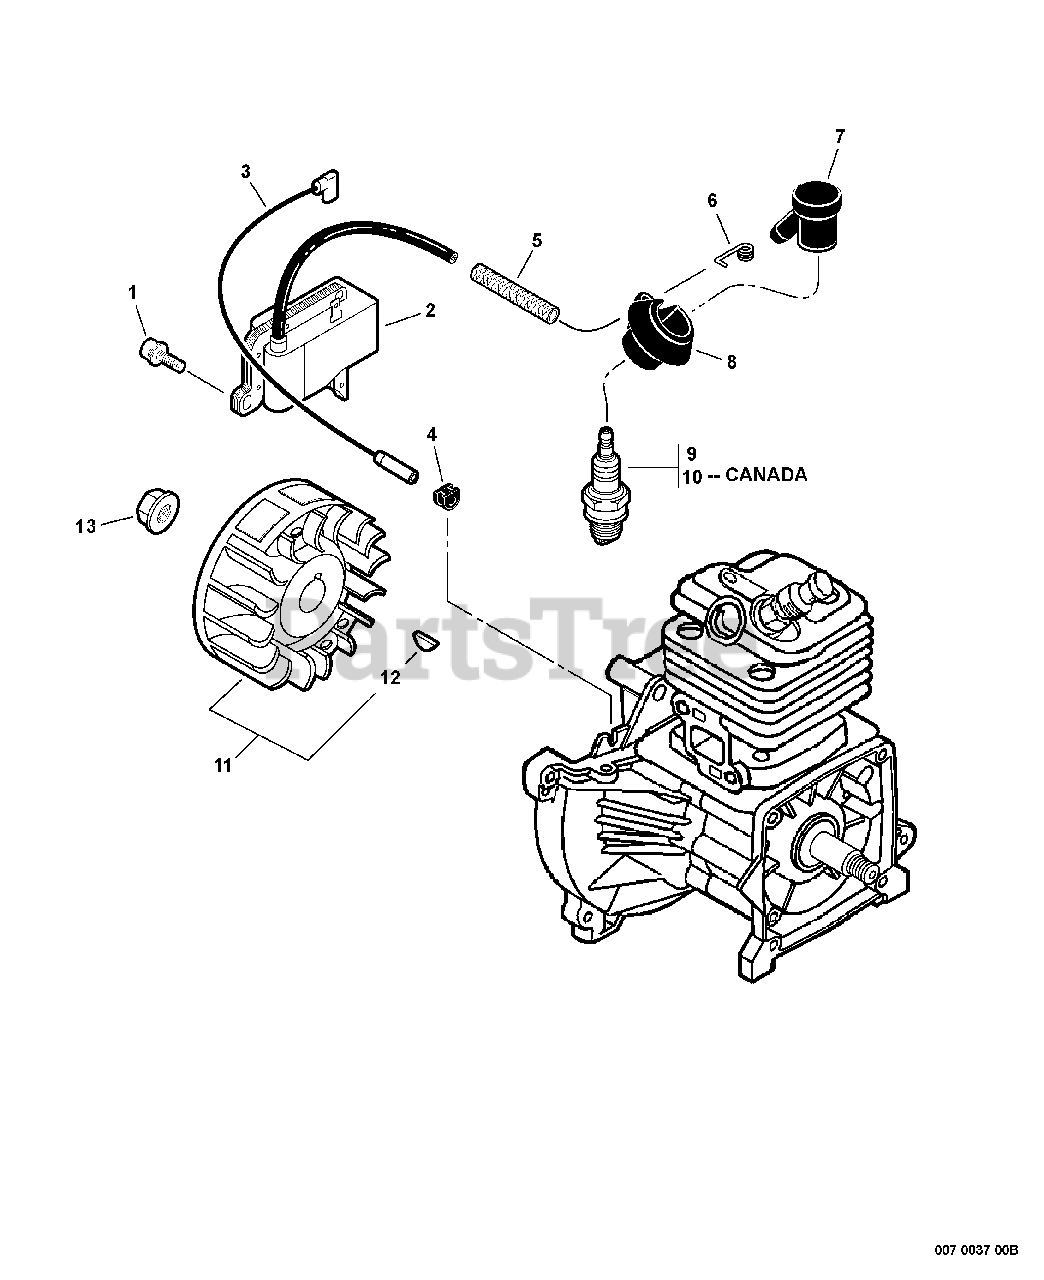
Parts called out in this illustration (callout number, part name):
1	SCREW - 5X20
2	COIL, IGNITION
3	LEAD - IGNITION
5	TUBE, INSULATOR
6	TERMINAL, SPARK PLUG CAP
7	CAP, SPARK PLUG
8	COVER, DUST
9	SPARK PLUG -- BPM-7A
10	SPARK PLUG -- BPMR-7A
11	FLYWHEEL KIT
12	KEY - 3X14
13	NUT - 10 -- FLANGE
